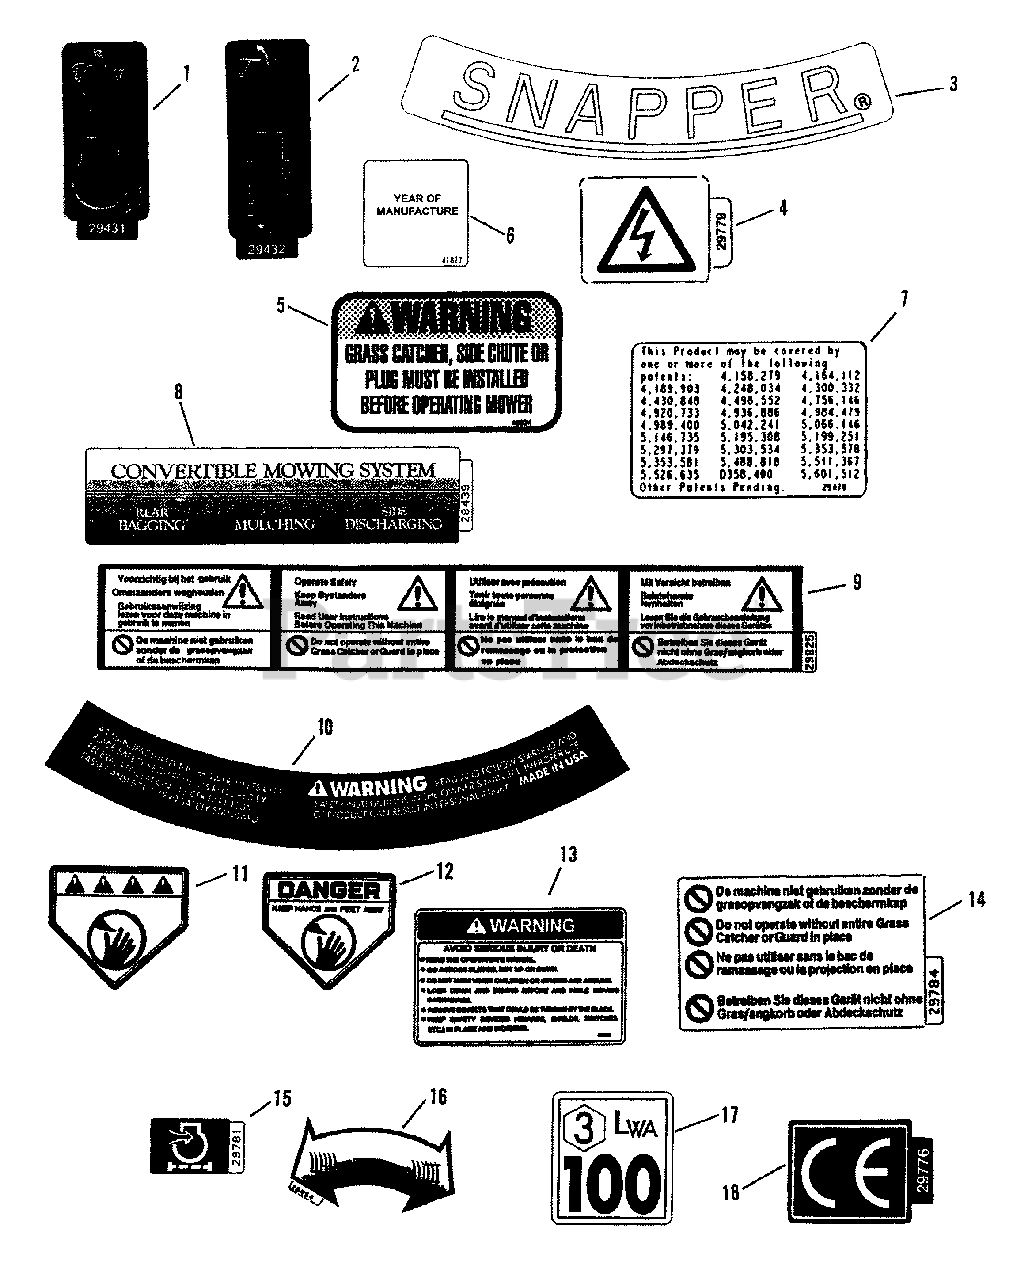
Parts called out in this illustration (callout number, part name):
1	DECAL, (OPC) Operator Presence Control
2	DECAL, Ground Drive
3	DECAL, Deck "SNAPPER" (Curved)
4	DECAL, Spark Plug International Symbol
5	DECAL, Chute/Deflector Warning
6	DECAL, Year of Manufacture
7	DECAL, Patent Numbers
8	DECAL, Convertible Mower
9	DECAL, - WARNING
10	DECAL - WARNING (Deck)
11	DECAL - WARNING (Deck)
12	DECAL - DANGER
13	DECAL, Warning
14	DECAL - DANGER
15	DECAL, Air Filter International Symbol
16	DECAL, Height Adjustment
17	DECAL, Noise
18	DECAL, Euro Community (CE)
